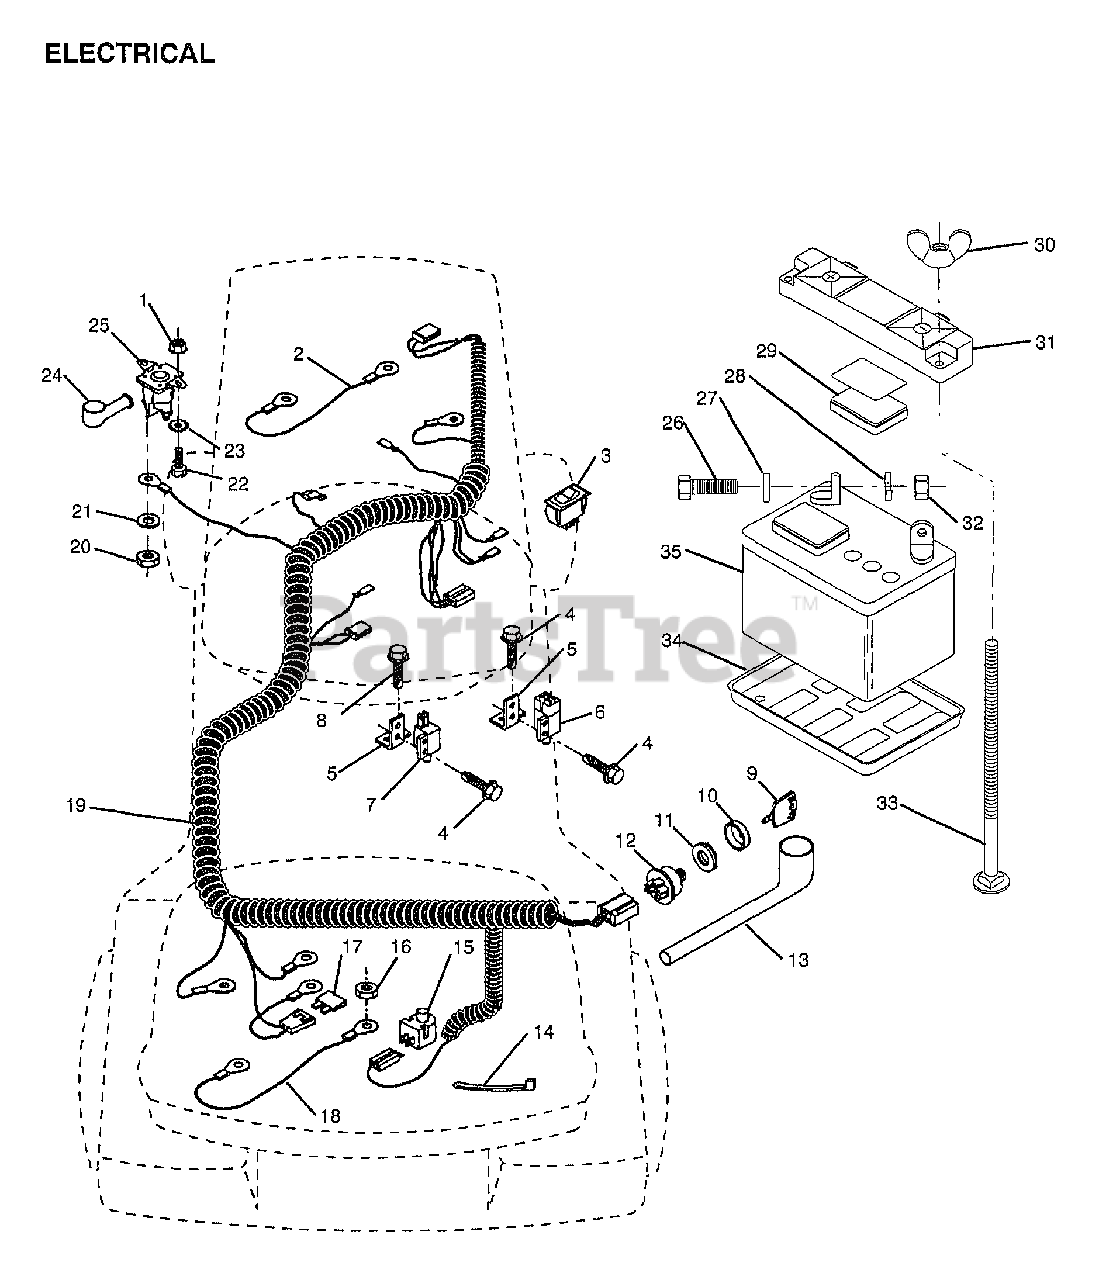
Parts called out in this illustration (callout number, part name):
1	NUT
2	CABLE LTV
3	SWITCH LT
4	SCREW
5	BRACKET LT
6	SWITCH INTERLOCKT
7	SWITCH-INTER. GT
8	SCREW
9	KEY
11	NUT IGNITION
13	COVER IGNITION SW
14	WIRE TIE
15	SWITCH SEAT
17	FUSE HYT
20	NUT
22	BOLT
26	BOLT LT
27	WASHER
28	LOCKWASHER
29	"CAP,BATTERY "
33	BOLT
34	"TRAY T, BATTERY"
